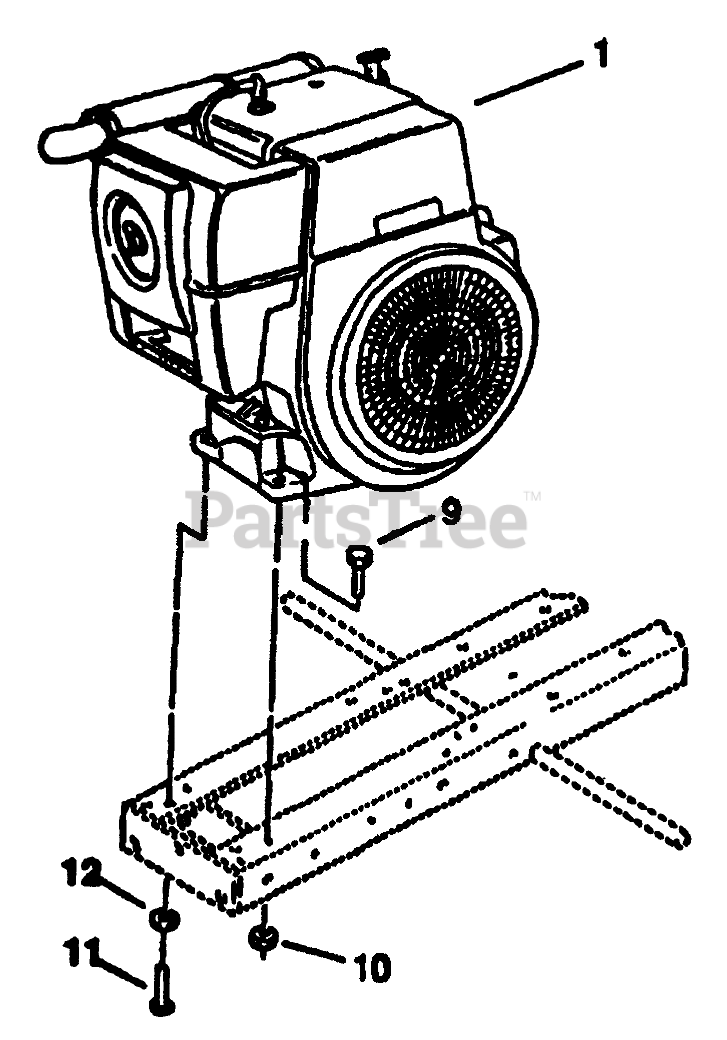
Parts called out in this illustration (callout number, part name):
1	Engine-12HP Kohler M-12-S Spec 471527
9	SCREW-HH
10	NUT-LOCK, NI
11	SCREW-HH
12	WASHER-LOCK
